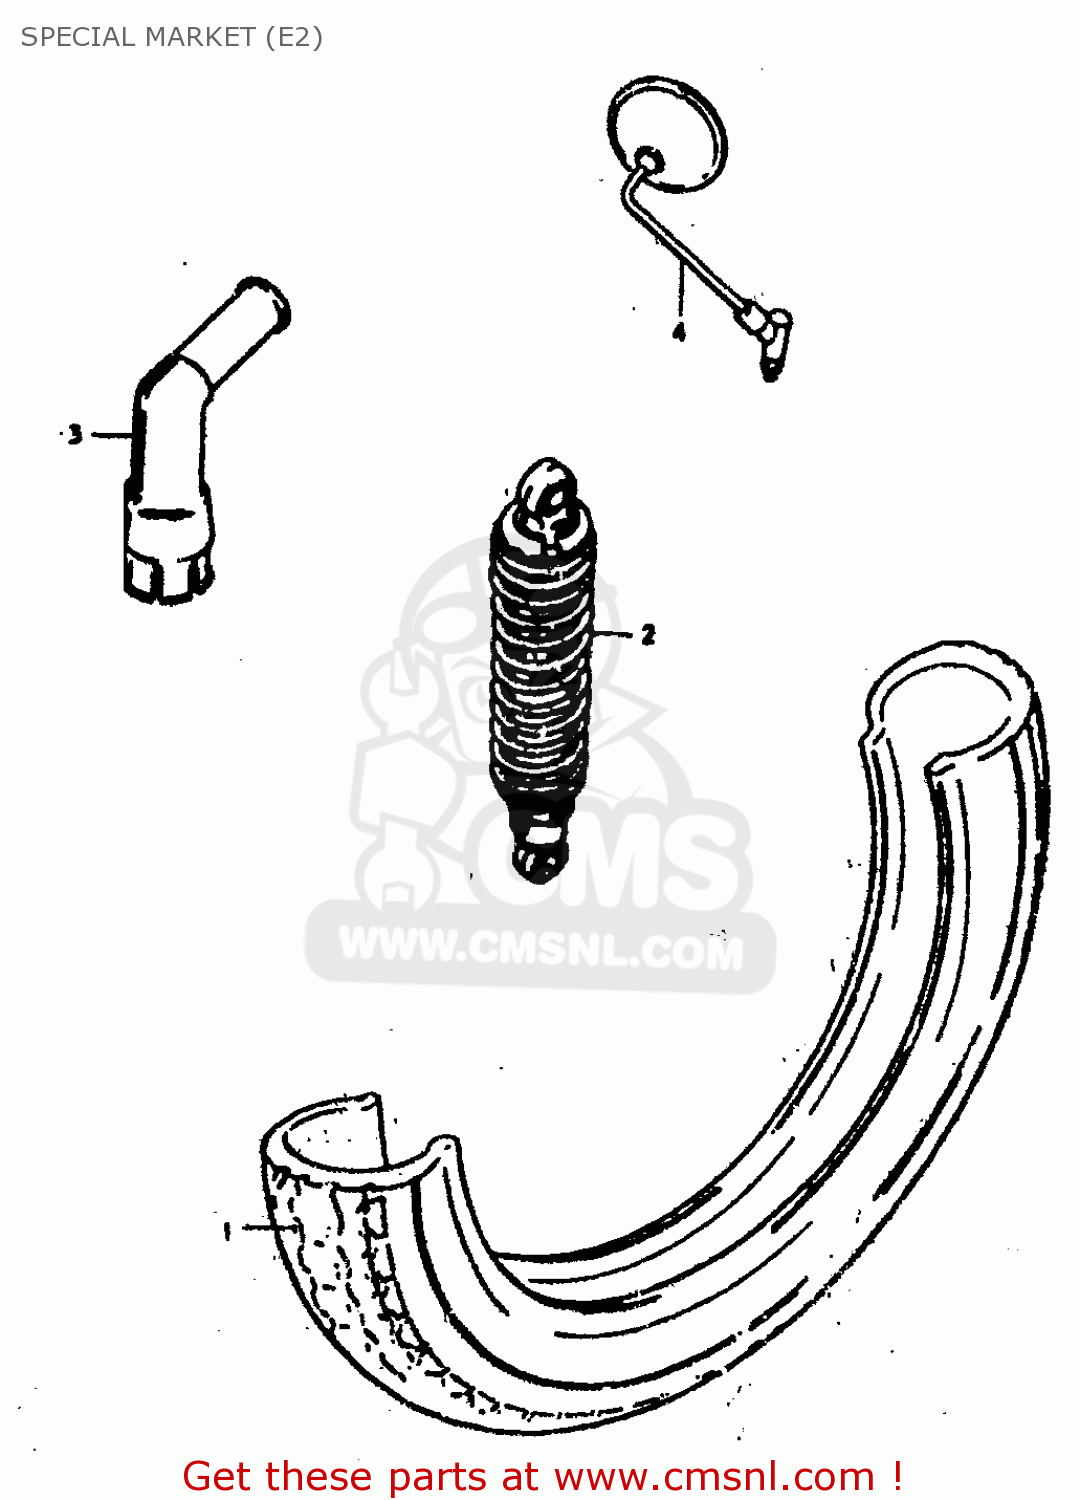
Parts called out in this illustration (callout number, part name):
1	TIRE (3.00S18) DUNLOP
2	SHOCK ABSORBER,REAR
3	CAP, SPARK PLUG (S)
4	MIRROR ASSY,RH
